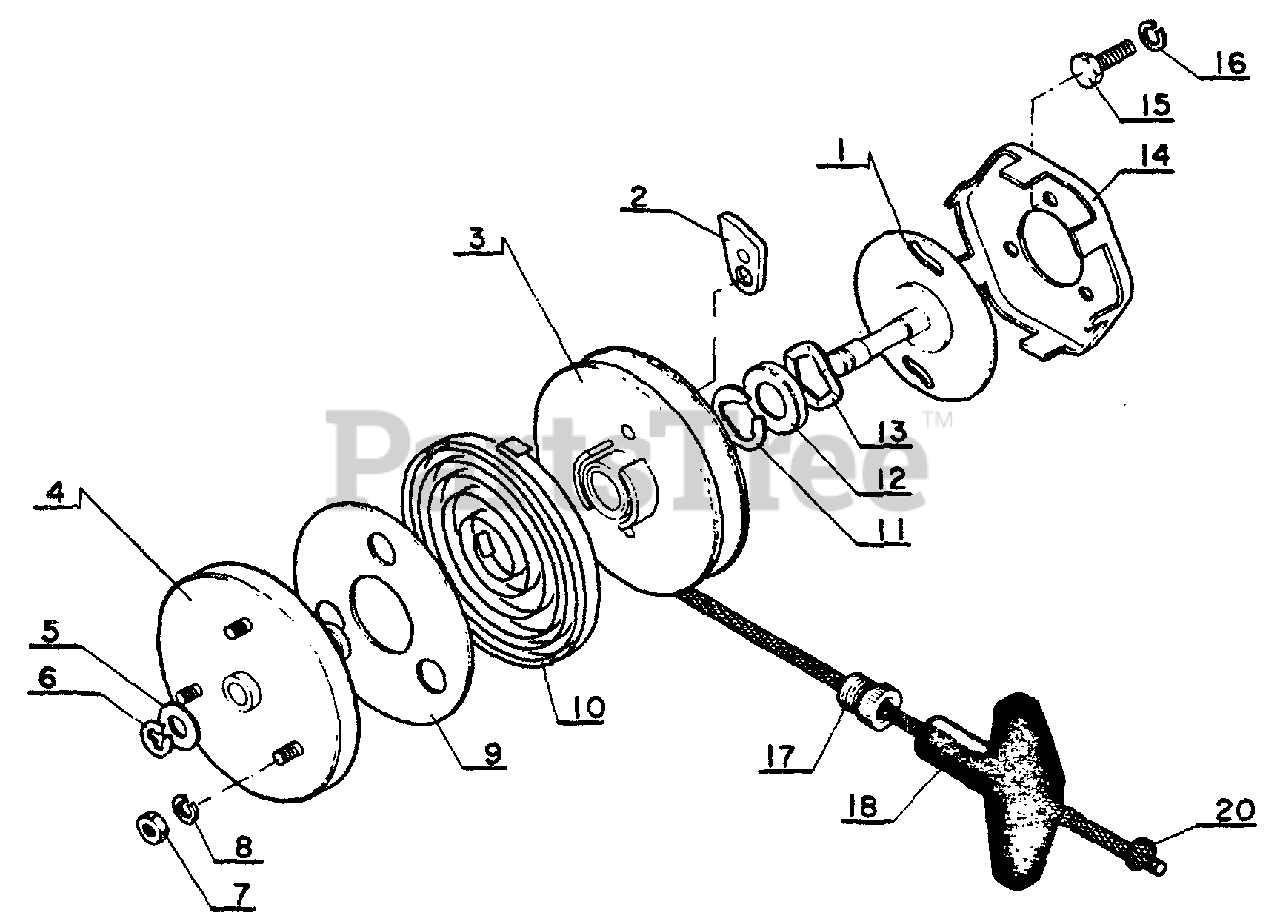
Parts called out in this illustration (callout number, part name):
1	PLATE, GUIDE
2	PAWL, STARTER
3	REEL, ROPE
4	RETAINER, SPRING
6	RING, RETAINING - 6
8	LOCKWASHER - 5
9	PLATE, STARTER
10	SPRING, REWIND
11	RING, RETAINING - 12
14	CATCHER, PAWL
15	BOLT - 6X14
16	LOCKWASHER - 6
17	GUIDE, ROPE
18	GRIP, STARTER
20	ROPE, STARTER
